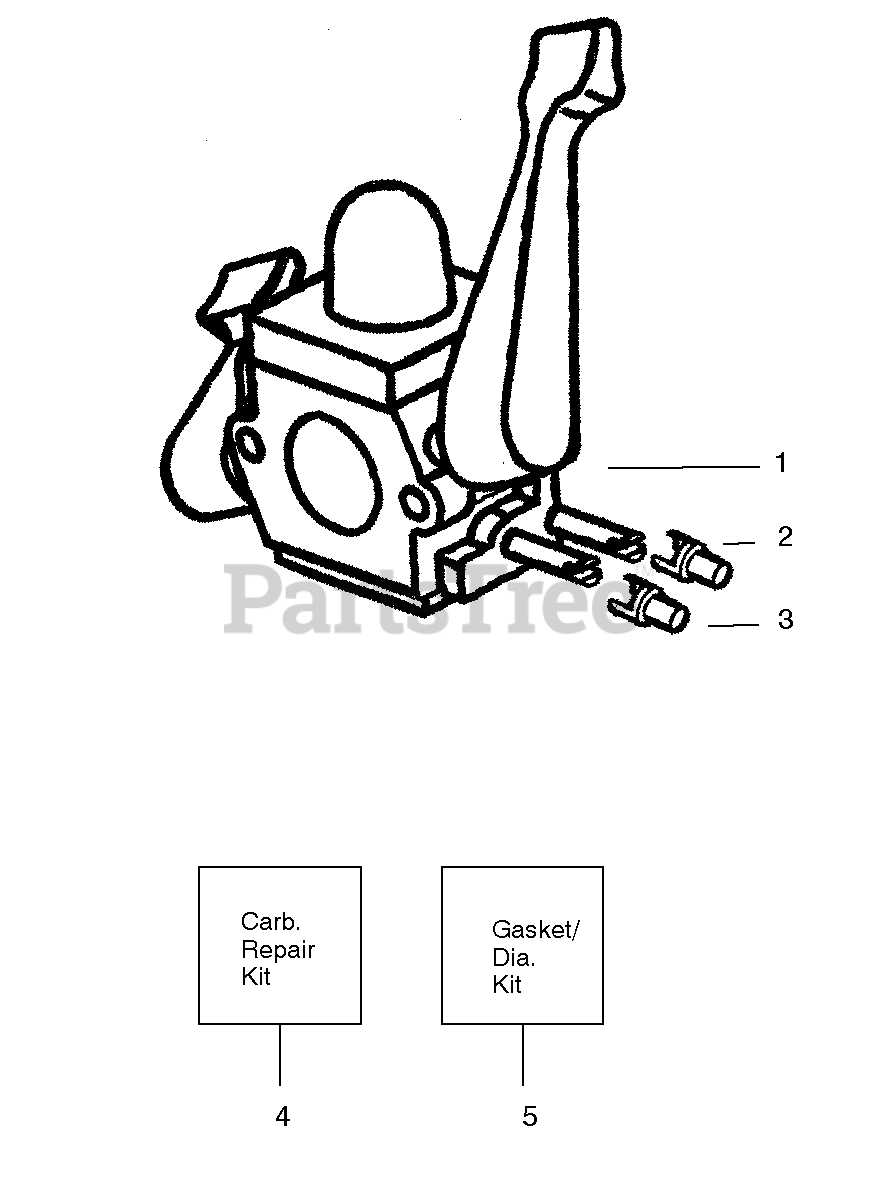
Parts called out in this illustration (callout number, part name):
1	Assy-Carb. Zama (C1Q-W11)
2	Cap-Limiter (high) brown
3	Cap-Limiter (low) tan
4	Kit-Carb. Repair
5	Kit-Carb. Gasket (Zama)
